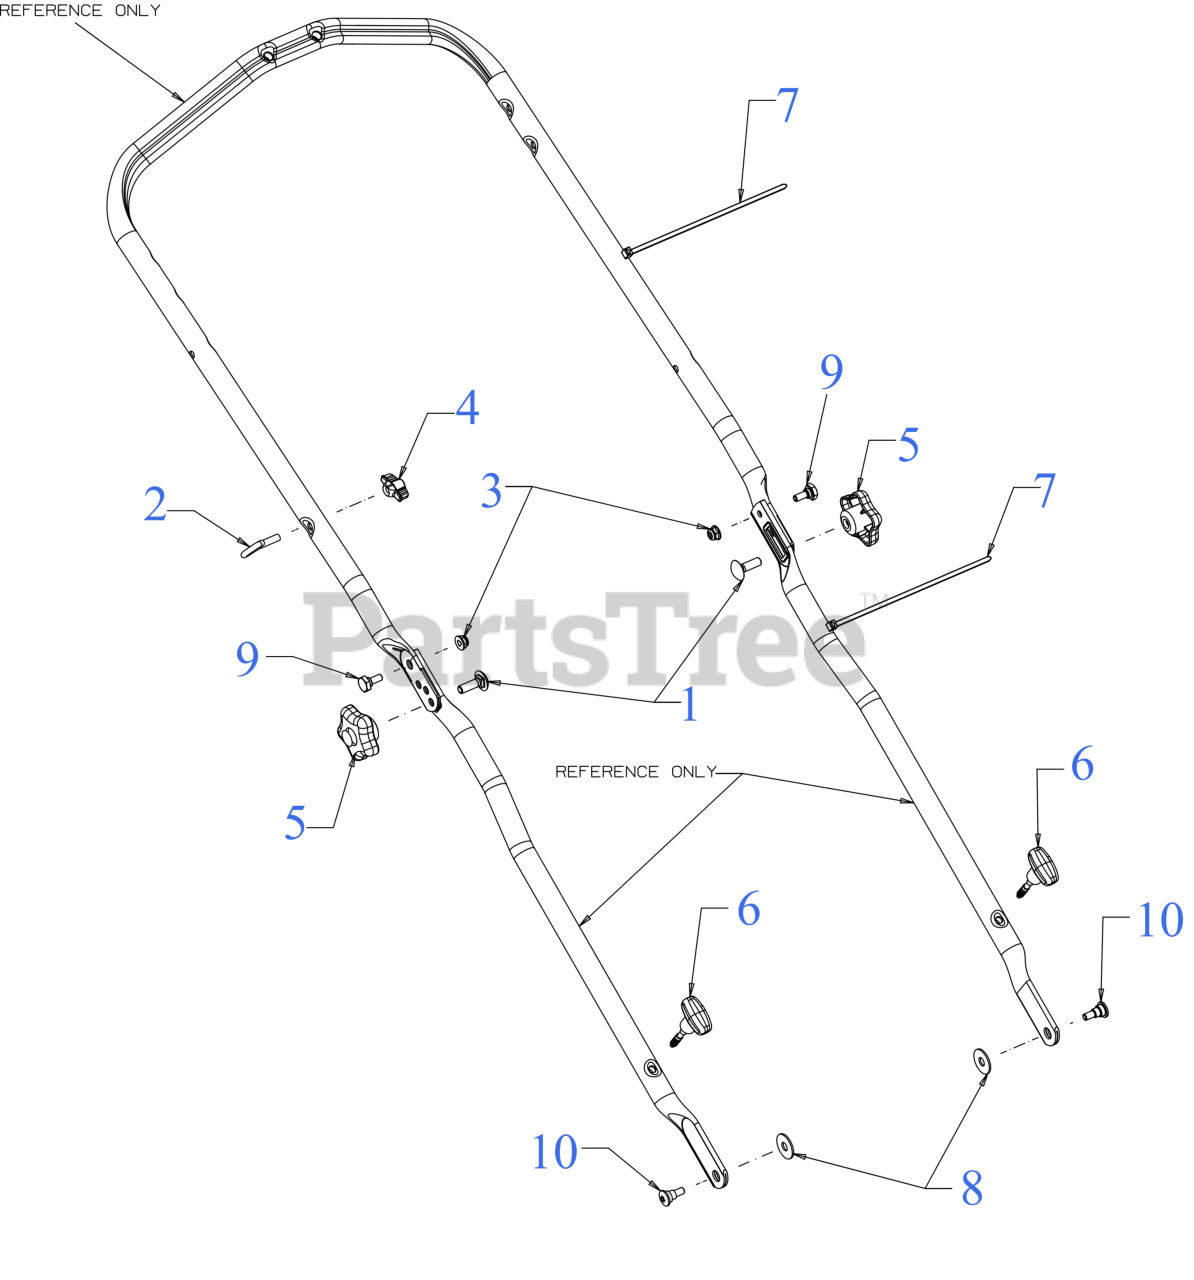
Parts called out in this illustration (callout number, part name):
1	SCREW 5/16-18 x 1.00 GR5
2	EYEBOLT 1/4-20
3	FLANGE LOCK NUT
4	HANDLE KNOB
5	STAR KNOB- YELLOW
6	WING KNOB 1/4-20 x 1.80
7	7" CABLE TIE
8	FLAT WASHER 344X1.00
9	SHOULDER SCREW
10	SHOULDER SCREW .450X .188X 1/4-20
